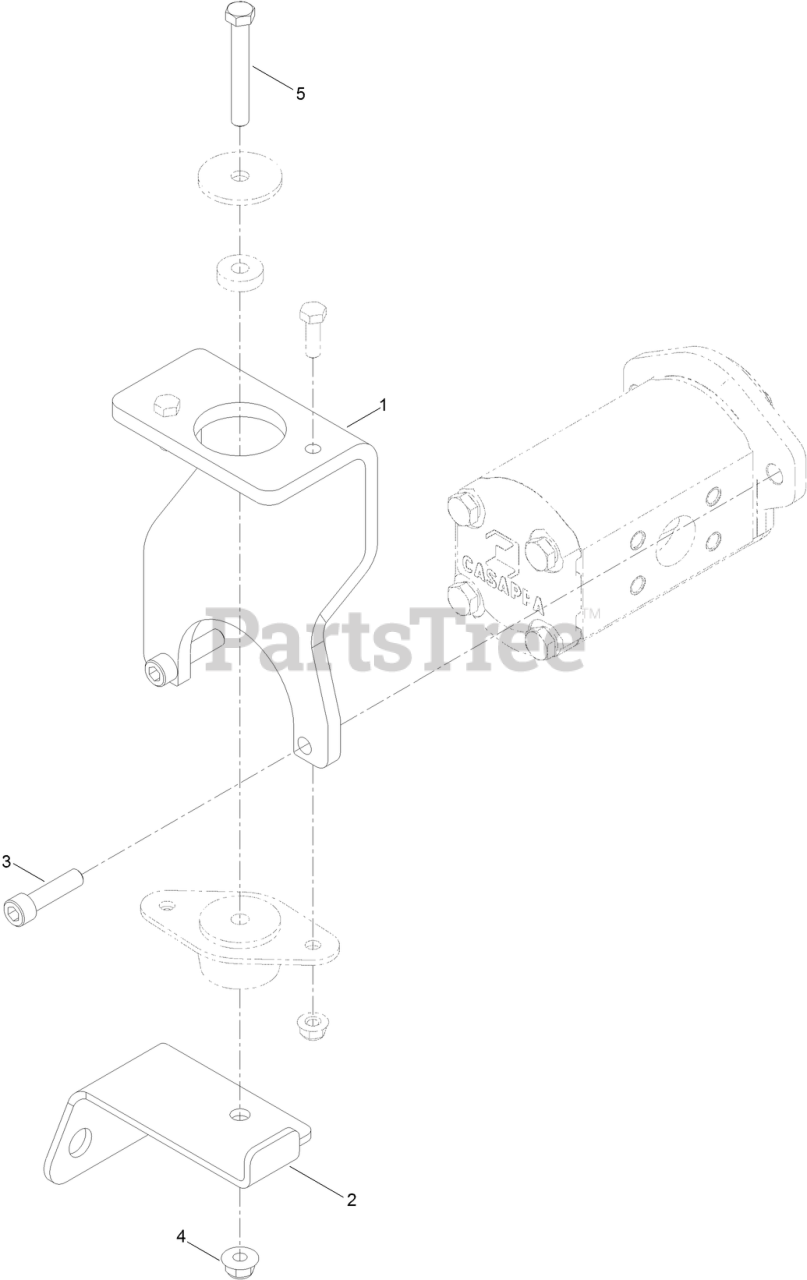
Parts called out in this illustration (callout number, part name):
1	BRACKET-SUPPORT, PUMP
2	BRACKET-BULKHEAD
3	SCREW-SH
4	NUT-HF, NI
5	SCREW-HH
